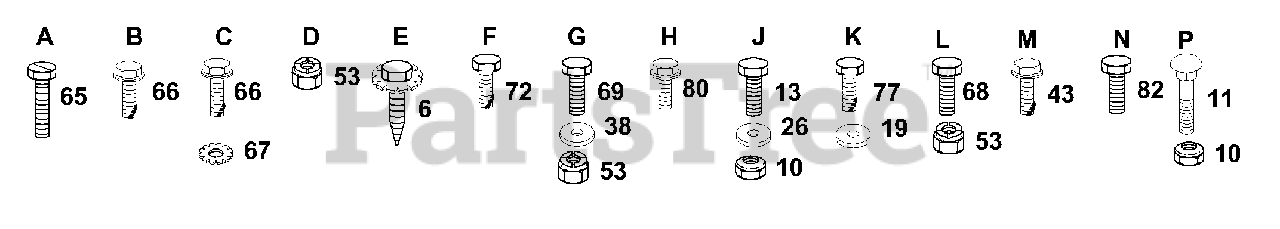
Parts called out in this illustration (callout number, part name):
6	Screw, Spider Lock, Hex #8 x 1/2
10	Locknut 5/16-18
11	Bolt, Carriage 5/16-18 x 3/4
13	Bolt, Hex Hd. 5/16-18 x 1
19	Washer 13/32 x 1 x 14 Gauge
26	Washer 11/32 x 3/4 x 12 Gauge
38	Washer 13/32 x 13/16 x 12 Gauge
43	Screw, Tap. Hex Hd, #10-24 x 1/2 Type T
53	Nut, Crownlock 3/8-16
65	Screw, Hex Thread Cut. 1/4-20 x 5/8
66	Screw, Hex Washer Thread Rolling 3/8-16 x 1-1/2
67	Washer, Lock External Tooth 3/8
68	Bolt, Hex 3/8-16 x 3/4
69	Bolt, Hex 3/8-16 x 1
72	Screw, Hex, Thdrol 3/8-16 x 3/4
77	Screw, Hex, Washer Thrdrol 5/16-18 x 3/4
80	Screw, Hex, Washer Thrdrol 1/4-20 x 1/2
82	Bolt, Metric
